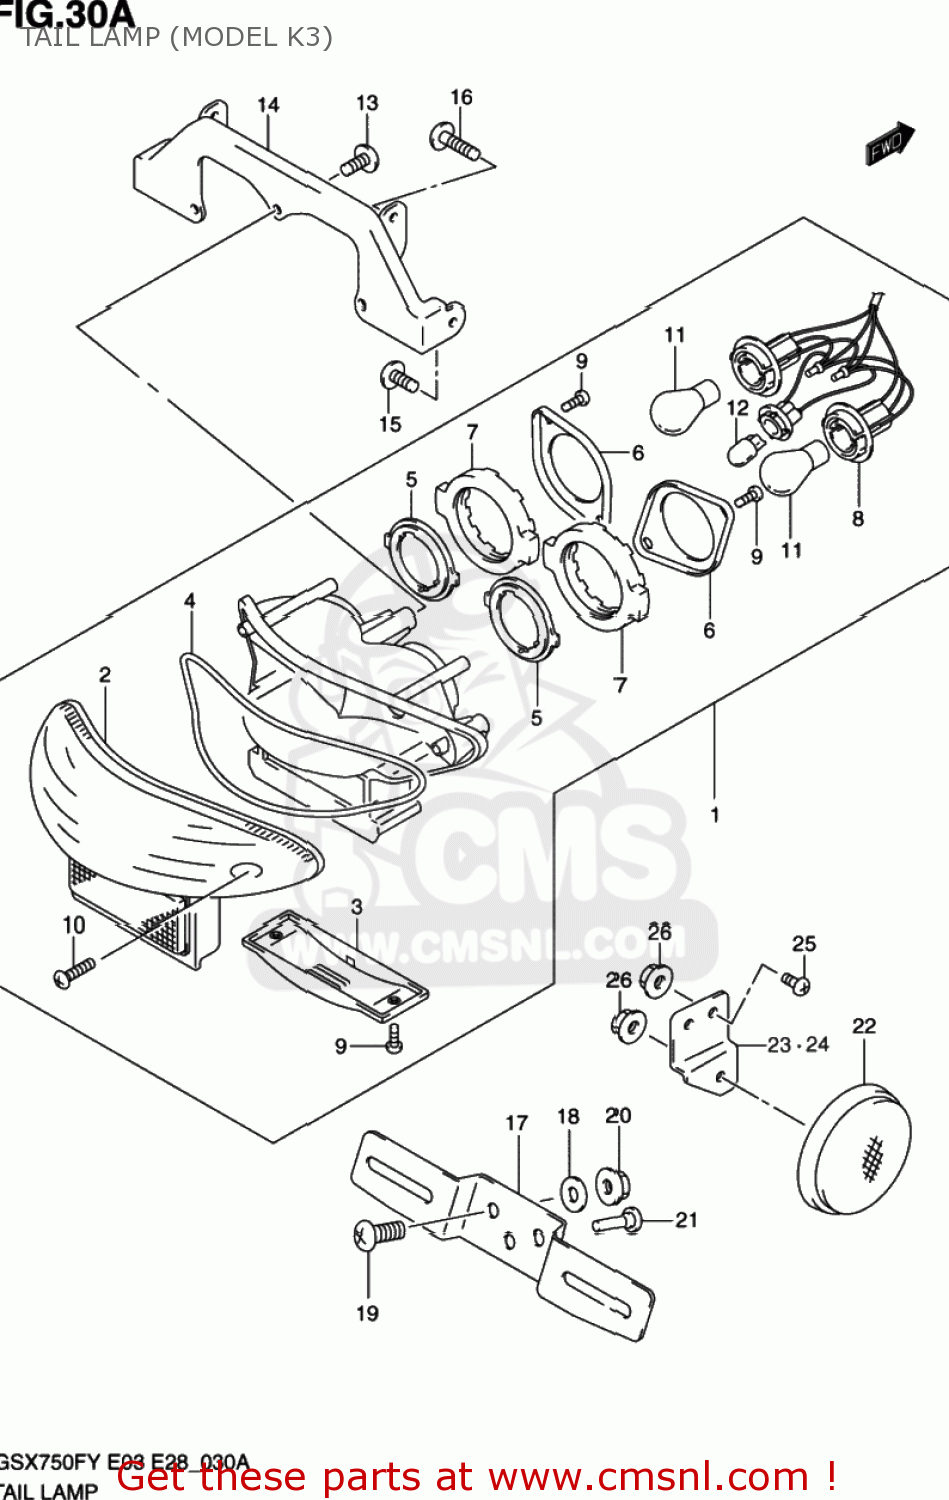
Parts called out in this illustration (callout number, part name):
1	LAMP ASSY,RR COMBINATION
2	LENS
3	LENS,LICENSE LAMP
4	GASKET (NAS)
5	PLATE NO.1
6	PLATE NO.2
7	CUSHION
8	SOCKET & CORD
9	SCREW
10	SCREW
11	BULB(12V21/5W)
12	BULB(12V5W)
13	SCREW
14	BRACKET,RR COMBINATION LAMP
15	SCREW
16	SCREW
17	BRACKET,LICENSE PLATE
18	WASHER(6.5X20X1.6)
19	SCREW
20	NUT
21	CUSHION
22	REFLECTOR ASSY,RR SIDE
23	BRACKET,RR SIDE RR,R
24	BRACKET,RR SIDE RR,L
25	SCREW
26	NUT
